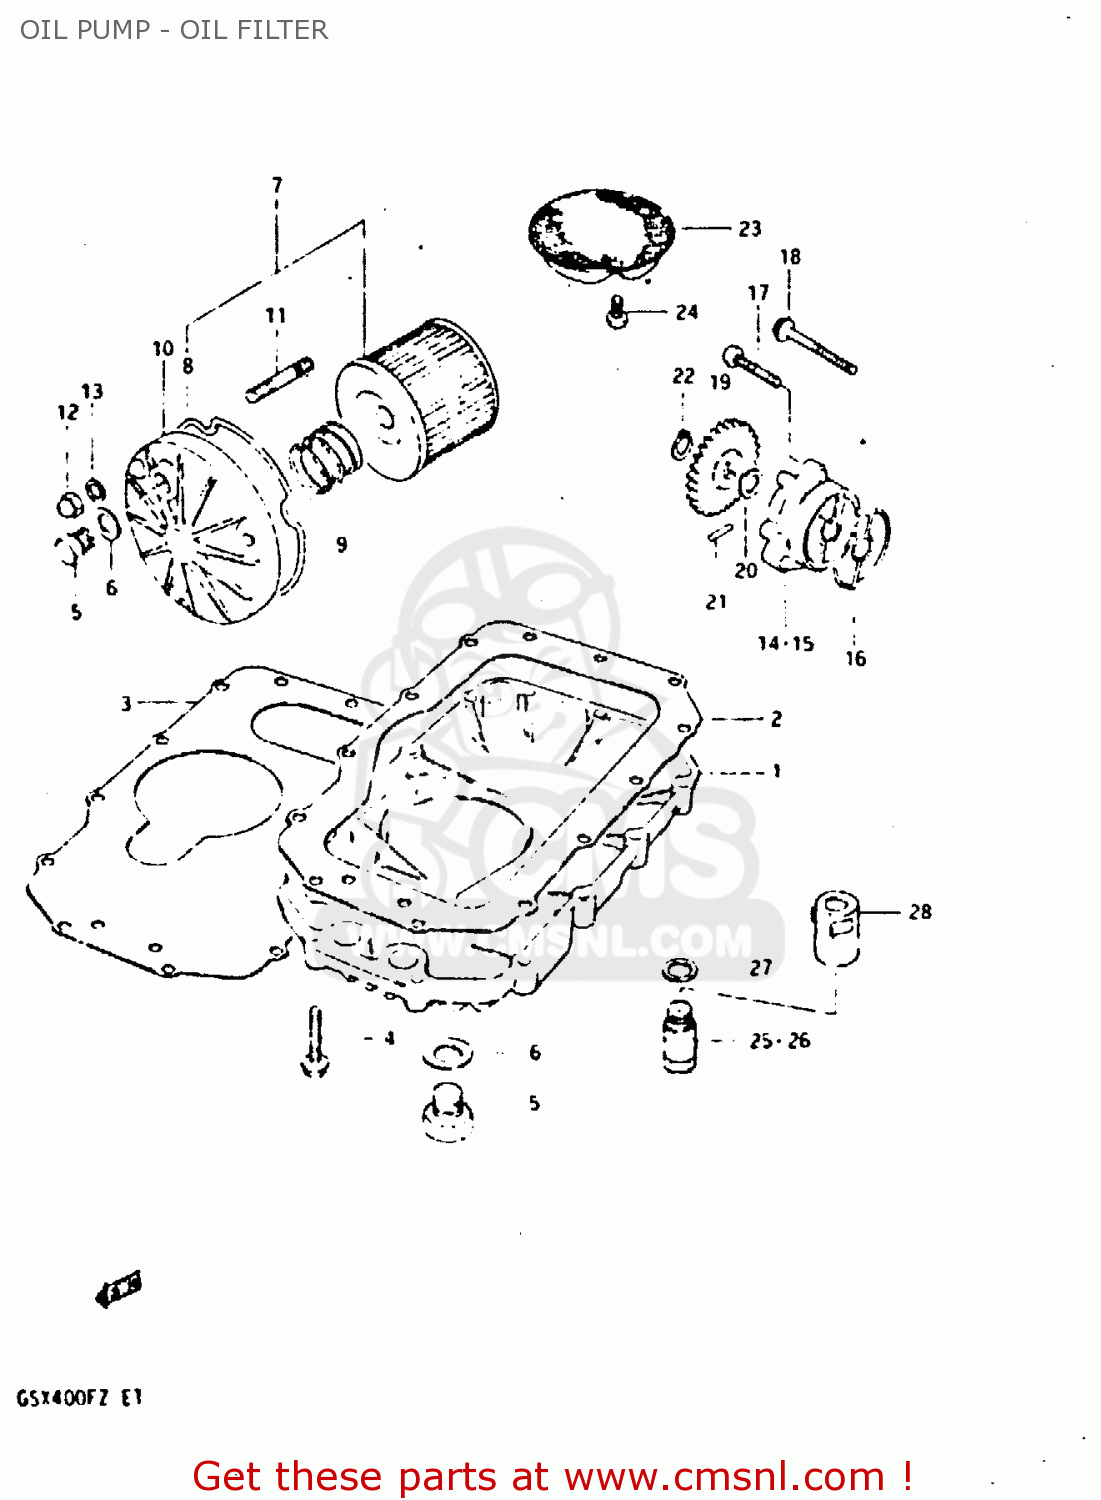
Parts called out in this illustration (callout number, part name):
1	PAN, OIL
2	GASKET
3	GASKET,OIL PAN (MCA)
4	BOLT
5	PLUG
6	GASKET(14X19.2X2) (NAS)
7	ENGINE OIL FILTER SET
8	O RING,OIL FILTER CHAMBER CAP
9	SPRING
10	CAP,OIL FILTER
11	STUD 6X20
12	NUT
13	WASHER
14	PUMP ASSEMBLY,OIL
15	PUMP ASSY,ENGINE OIL
16	O-RING,OIL PUMP
17	SCREW
18	BOLT(6X32)
19	GEAR,ENG OIL PUMP DRIVEN
20	SHIM
21	PIN(4X15.8)
22	CIRCLIP
23	STRAINER,ENGINE OIL
24	SCREW 6X12
25	REGULATOR ASSEMBLY,ENGINE
26	REGULATOR, ENGINE OIL
27	WASHER
28	GUIDE, REGULATOR
